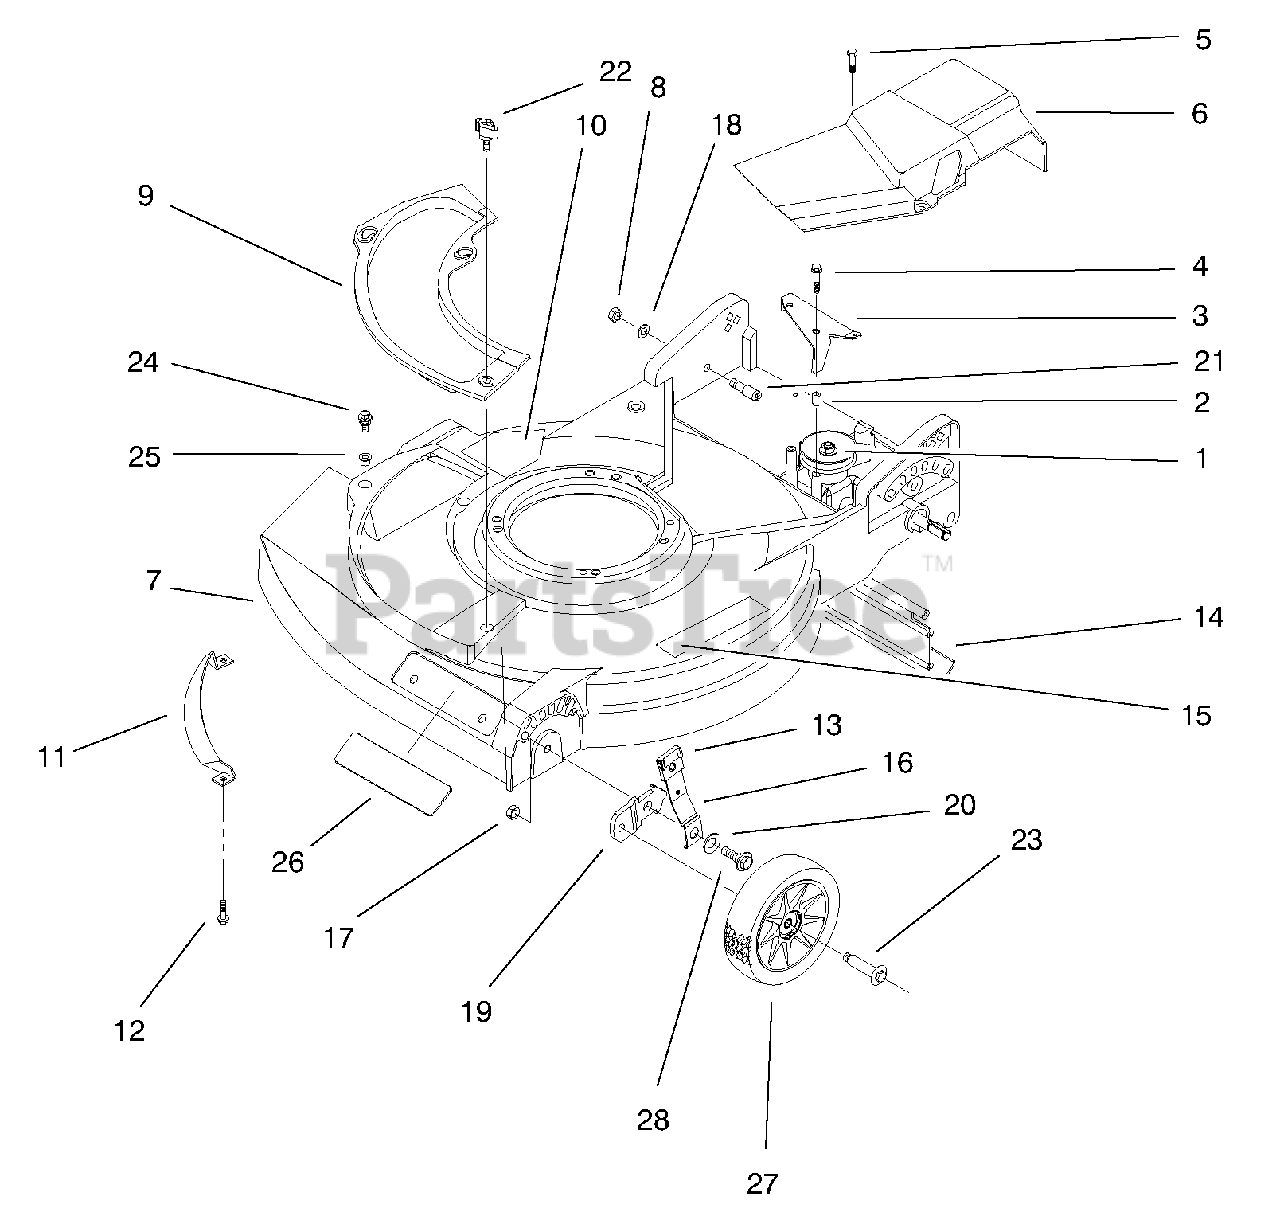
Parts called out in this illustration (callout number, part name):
1	ASM-Gear Case
2	Bushing-Spacer
3	Bracket-Actuator
4	Screw
5	Screw-Thread Forming
6	Cover-Drive
7	Housing-21" Sp
8	Nut-Lock
9	Plate-Cover
10	Decal-Danger
11	Toe Bar 21
12	Screw-HWH
13	Knob-Height Adjust
14	Shield-Trailing
15	Decal-Warning
16	ASM-Spring Arm
17	Nut-Lock
19	Bracket-Wheel Height Adj
20	Washer-Spring
21	Bolt-Shoulder
22	Knob-Cover Plate
23	Bolt-Wheel
24	Screw-Sems
25	Grommet-Plastic
26	Decal-Deck
27	Wheel & Tire
28	Bolt-Shoulder
